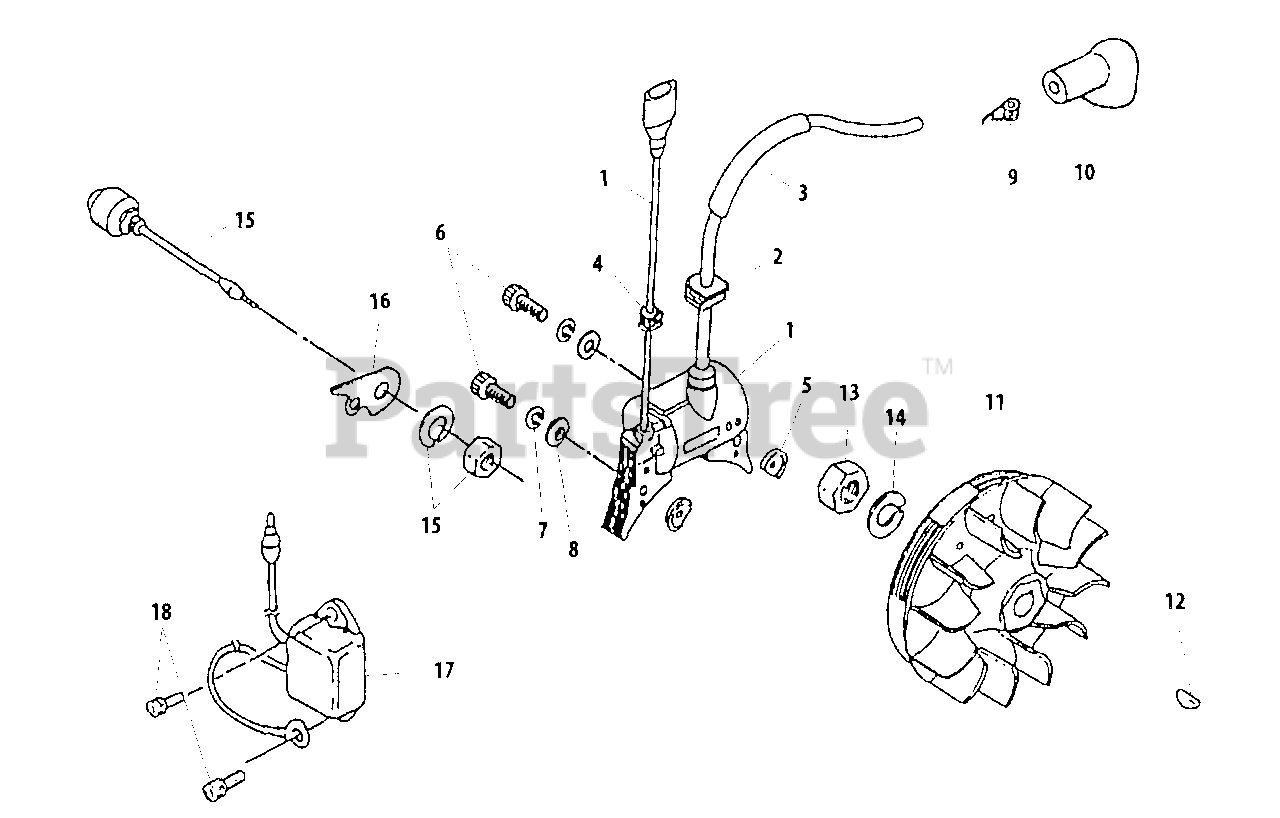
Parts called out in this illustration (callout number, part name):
1	COIL, IGNITION
2	GROMMET
3	TUBE, INSULATOR
4	GROMMET
5	COLLAR 4
6	BOLT
7	WASHER, SPRING 4 MM
8	WASHER 4.3×9.6×0.8
9	TERMINAL, SPARK PLUG
10	CAP, SPARK PLUG
11	FLYWHEEL
12	KEY, WOODRUFF 3×10
13	NUT 10×1.25
14	WASHER, SPRING 10
15	SWITCH, ON-OFF
16	BRACKET
17	ELECTRONIC UNIT
18	BOLT M4×12
